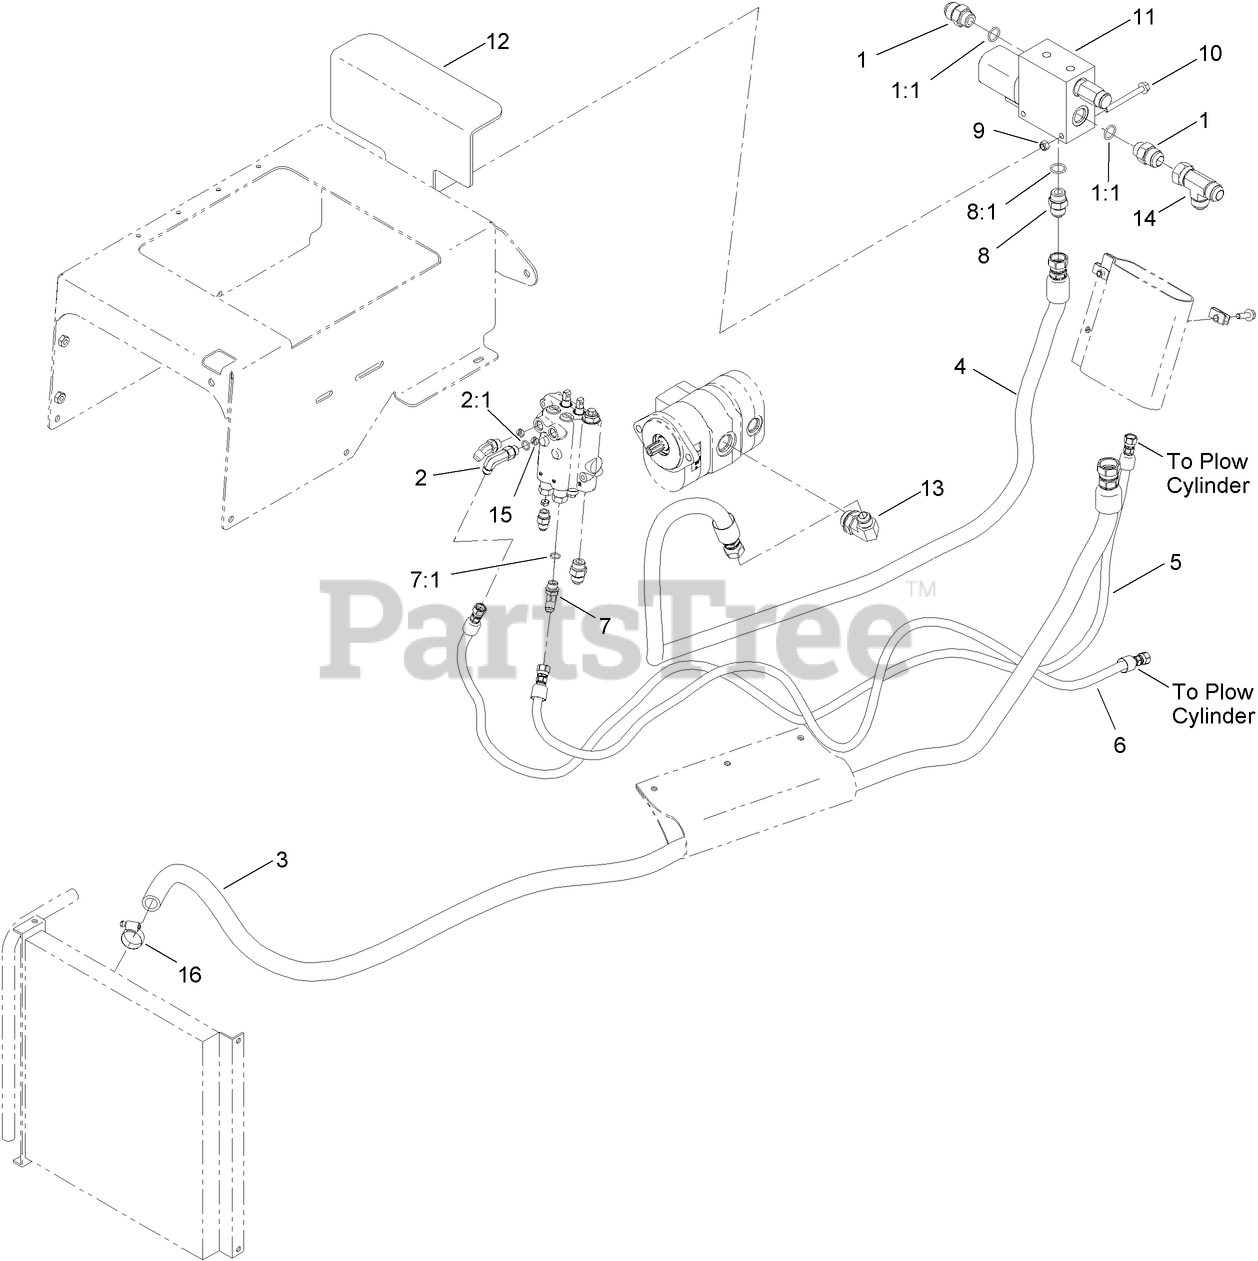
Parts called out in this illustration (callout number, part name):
1	FITTING-STRAIGHT
1:1	O-RING
2	FITTING-ADAPTOR, 90 DEG
2:1	O-RING
3	HOSE ASM
4	HOSE ASM
5	HOSE ASM
6	HOSE ASM
7	FITTING-ELBOW, 45 DEG
7:1	O-RING
8	FITTING-STRAIGHT
8:1	O-RING
9	NUT-LOCK, NI
10	SCREW-HHF
11	3 WAY HYD PLOW VALVE ASM
12	PLATE-HEAT SHIELD
13	ADAPTOR-ELBOW
14	FITTING-TEE
15	ORIFICE
16	CLAMP-HOSE
